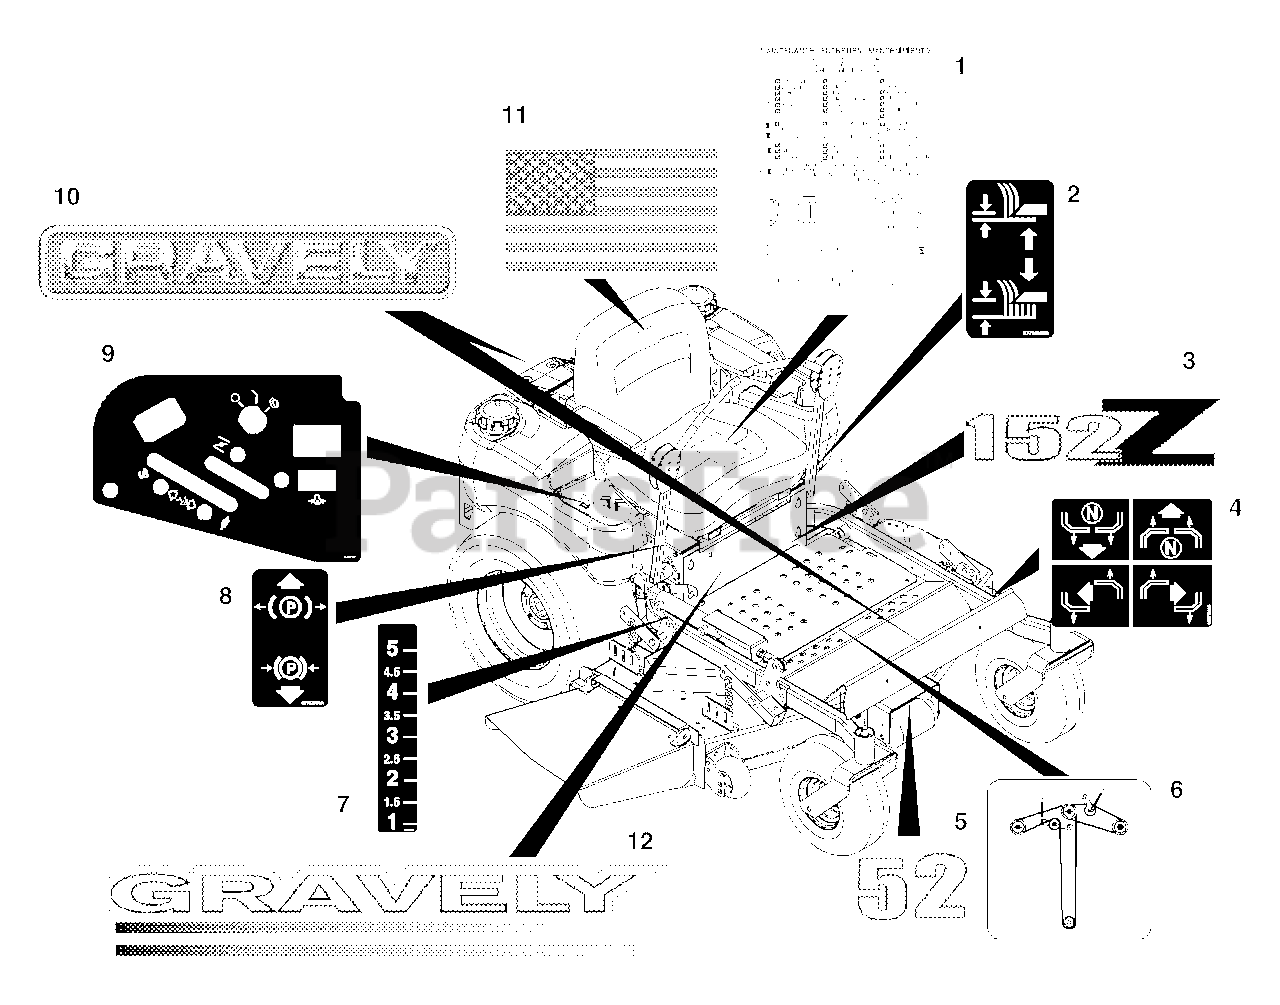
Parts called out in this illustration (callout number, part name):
1	Decal, Service Instructions
2	Decal, Lift Lever
3	Decal, PM 152Z (044)
3	Decal, PM 144Z (042)
3	Decal, PM 148Z (043)
3	Decal, PM 160Z (051)
4	Decal, Instructional Steering
5	Decal, 52 (044)
5	Decal, 44 (042)
5	Decal, 48 (043)
5	Decal, 60 (051)
6	Decal, Belt Diagram
7	Decal, Height of Cut
8	Decal, Parking Brake Lever
9	Decal, Control Panel
10	Decal, 15" Gravely Logo
11	Decal, American Flag
12	Decal, ZT Hood
